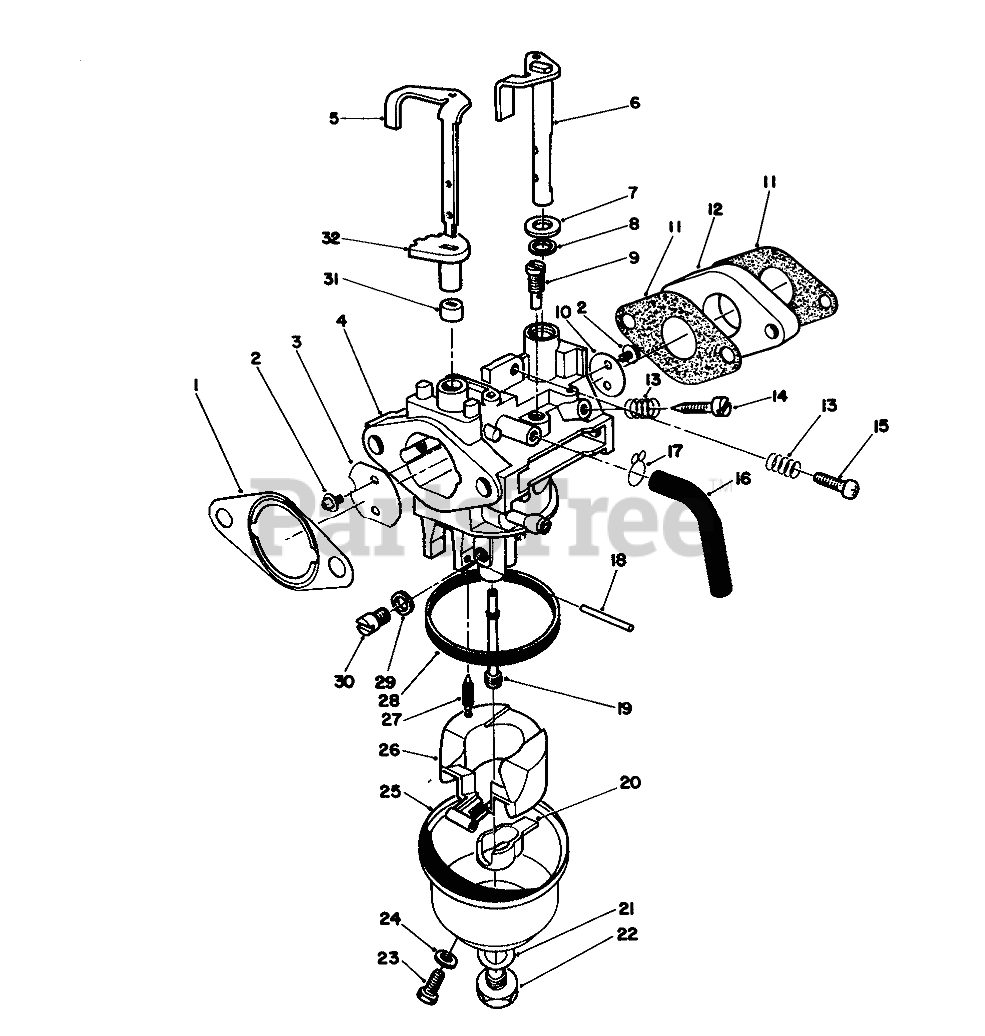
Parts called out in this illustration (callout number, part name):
1	GASKET F/W ENGINE
2	Screw
3	VALVE
4	Body-Carburetor
5	Shaft-Choke Valve
6	SHAFT
7	WASHER
8	Seal-Throttle Shaft
9	PILOT JET
10	VALVE
11	Gasket-Carburetor
12	CARB INSULATOR
13	SPRING-PILOT SCREW
14	ADJUSTER
15	SCREW
17	CLAMP
18	Pin
19	NOZZLE
20	SPACER
21	GASKET
22	SCREW
23	SCREW
24	GASKET
26	FLOAT
27	NEEDLE
28	FLOAT BOWL GASKET
29	SPACER
30	MAIN JET
31	LOWER CHOKE RING
32	UPPER CHOKE RING
